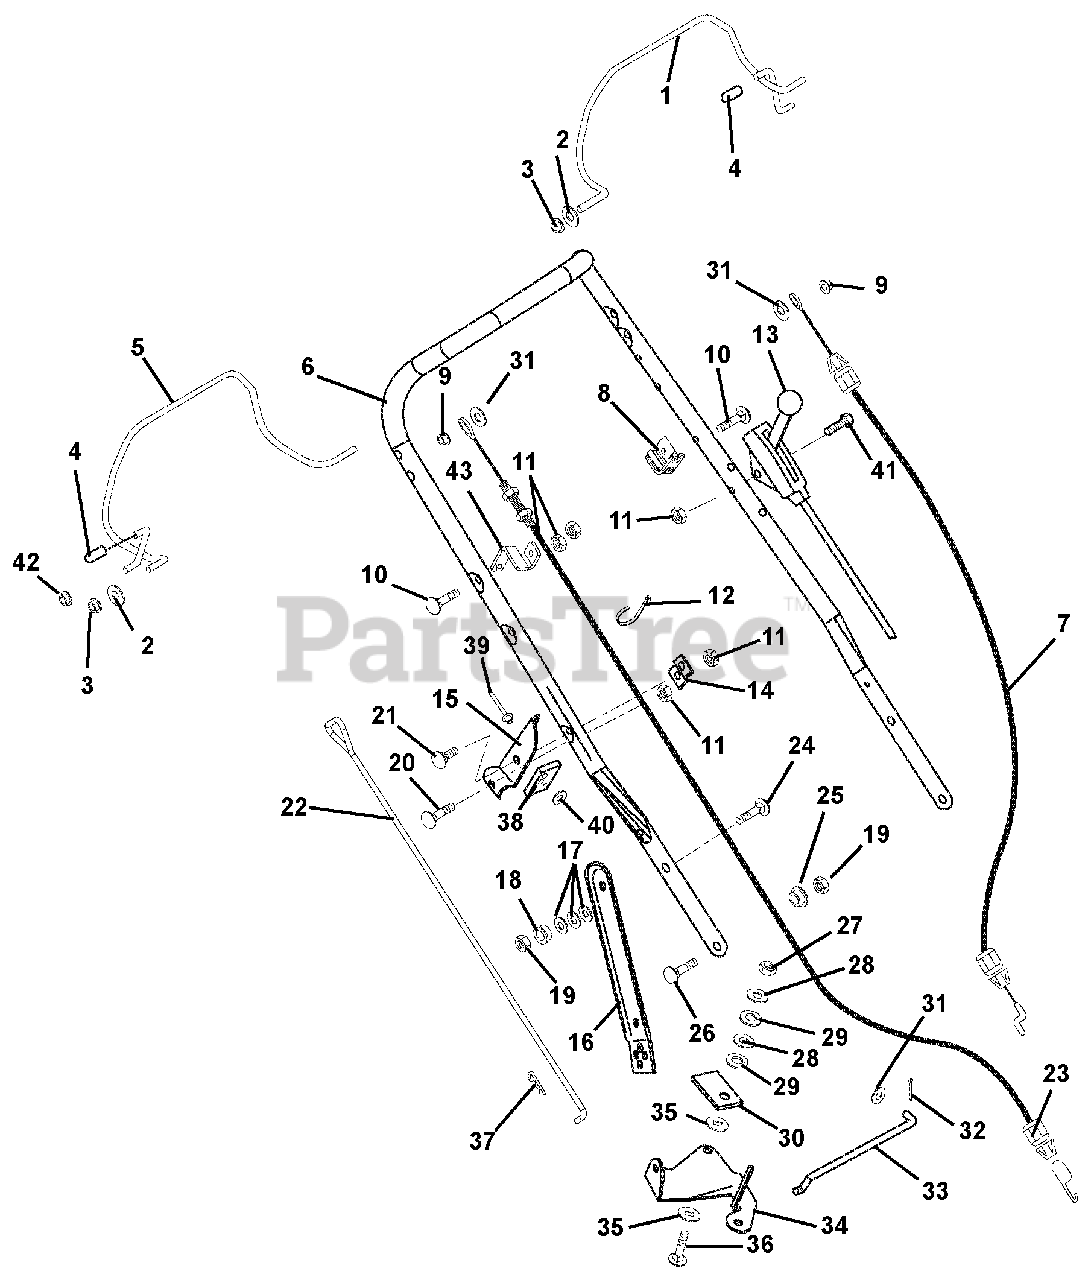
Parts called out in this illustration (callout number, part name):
1	Bail, Engine
2	Washer, Flat Steel .32 x .44 x .44 x .56 (911136, 137, 262, 263, 264, 265)
2	Washer, Flat Steel .32 x .44 x .44 x .56 (911260, 261)
3	Bushing, Flange .325 x .688 x .560 (911136, 137, 262, 263, 264, 265)
3	Bushing, Flange .325 x .688 x .560 (911260, 261)
4	Cap, Vinyl .25 I.D. (911136, 137, 262, 263, 264, 265)
4	Cap, Vinyl .25 I.D. (911260, 261)
5	Traction Bail (911136, 137, 262, 263, 264, 265)
6	Handlebar
7	Cable, OPC (911260, 261, 262, 263, 264, 265)
7	Cable, Engine Kawasaki (911136)
7	Cable, Engine Kawasaki (911137)
8	Cable, Anchor
9	Push Nut, .25 (911136, 137, 262, 263, 264, 265)
9	Push Nut, .25 (911260, 261)
10	Bolt, Round Head Square Neck .25-20 x 1.25 (911136, 137, 262, 263, 264, 265)
10	Bolt, Round Head Square Neck .25-20 x 1.25 (911260, 261)
11	Nut, Locking Center .25-20 (911137, 264, 265)
11	Nut, Locking Center .25-20 (911136, 260, 261, 262, 263)
12	Cable Tie
13	Cable, Lockout Control (911137, 264, 265)
14	Brace, Speed Control (911136, 137, 262, 263, 264, 265)
15	Bracket, Speed Control (911136, 137, 262, 263, 264, 265)
16	Link, Handlebar Adjuster Left Hand
16	Link, Handlebar Adjuster Right Hand
17	Washer, Bellville Spring
18	Bushing, Flange .325 x .50 x .513 x .875
19	Nut, Locking Center .31-18
20	Bolt, Round Head Square Neck .25-20 x 1.38
21	Bolt, Round Head Square Neck .25-20 x .50 Grade
22	Rod, Speed Control (911136, 137, 262, 263, 264, 265)
23	Traction Cable (911136, 137, 262, 263, 264, 265)
24	Bolt, Round Head Square Neck .31-18 x 1.00 Grade 5
25	Shoulder Spacer
26	Bolt, Round Head Square Neck .31-18 x .75 Grade 5
27	Nut, Locking Center .38-16 (911136, 137, 262, 263, 264, 265)
28	Washer, Flat Steel .406 x .812 x .065 (911136, 137, 262, 263, 264, 265)
29	Washer, Lock .375 x .115 Heavy (911136, 137, 262, 263, 264, 265)
30	Pressure Flange (911136, 137, 262, 263, 264, 265)
31	Washer, Flat Steel .281 x .62 x .065 (911136, 137, 262, 263, 264, 265)
32	Pin, Cotter .06 x .50 (911136, 137, 262, 263, 264, 265)
33	Shift Link (911136, 137, 262, 263, 264, 265)
34	Bell Crank, Speed Control (911136, 137, 262, 263, 264, 265)
35	Friction Washer (911136, 137, 262, 263, 264, 265)
36	Bolt, Round Head Square Neck .38-16 x 1.25 (911136, 137, 262, 263, 264, 265)
37	Pin, Hair Internal .08 x .18 x 1.18 (911136, 137, 262, 263, 264, 265)
38	Support Pad
39	Rivet .187 x .575
40	Washer, Flat Steel .219 x .50 x .049
41	Bolt, Round Head Square Neck .25-20 x 2.00 Grade 5 (911137, 264, 265))
42	Nut, Push .312
43	Anchor, Cable (911136, 137, 262, 263, 264, 265)
